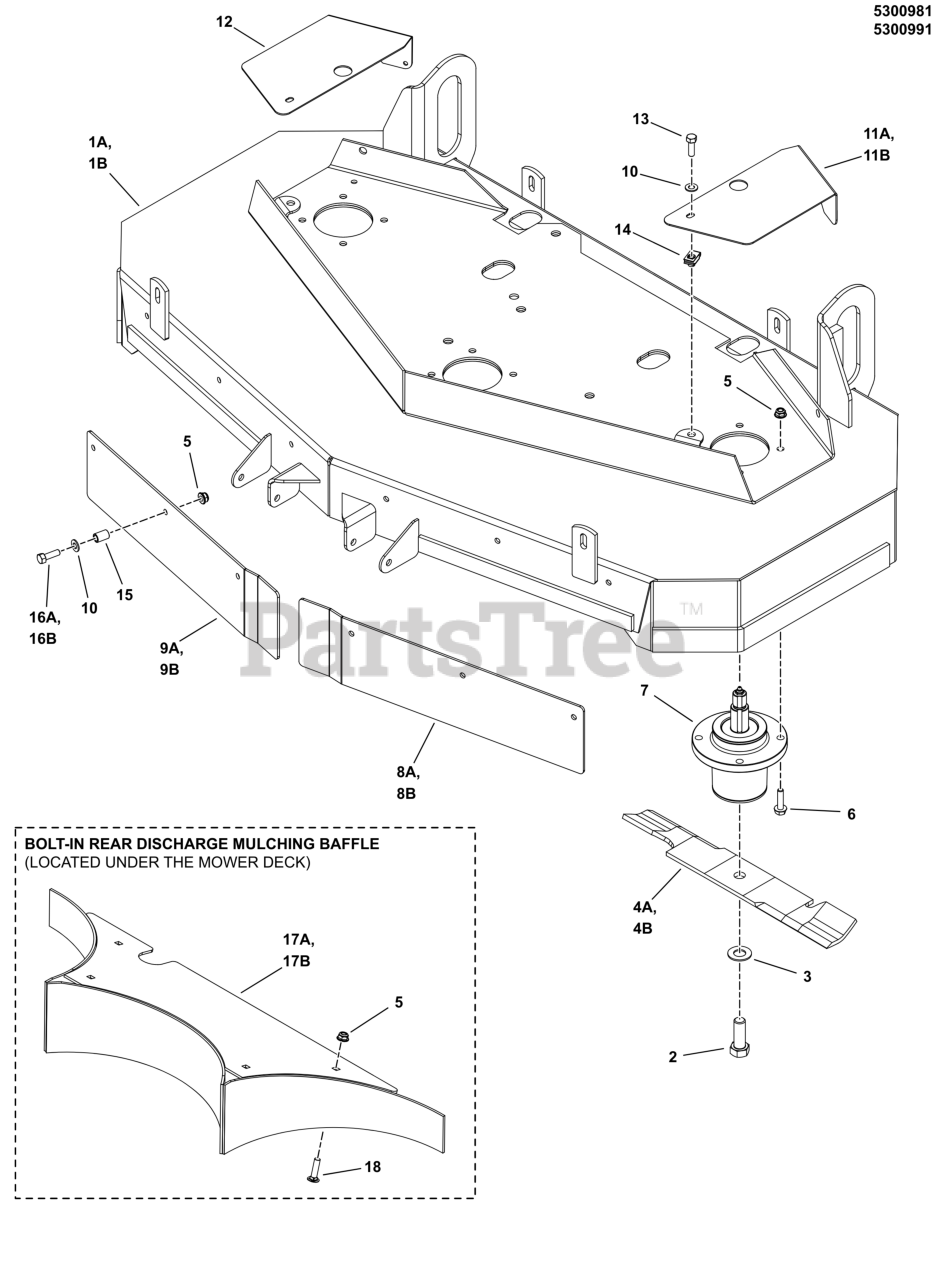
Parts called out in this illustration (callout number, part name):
1A	DECK SHELL W/DECALS
1B	DECK SHELL W/DECALS
2	BOLT, 5/8-11 X 1-3/4 GD8
3	WASHER, 5/8 GRADE 8, YZ
4A	BLADE SET, 48 DECK (SET OF 3 BLADES)
4B	BLADE, 18 (3) SET
5	NUT, 5/16-18 HEX NYLOCK FLANGE
6	BOLT, 5/16-18 X 1 1/4 FLANGE
7	ASSM, SPINDLE, LOW PROFILE
8A	BAFFLE, FRONT DISCHARGE, LH
8B	BAFFLE, FRONT DISCHARGE, LH
9A	BAFFLE, FRONT DISCHARGE, RH
9B	BAFFLE, FRONT DISCHARGE, RH
10	WASHER, 5/16" SAE
11A	GUARD, DECK, LH
11B	GUARD, DECK, LH
12	GUARD, DECK, RH
13	BOLT, 5/16-18 X 1 GD5 YZ
14	BODY CLIP, 5/16-18-7GA MATERIAL
15	SPACER, .33 X .50 X .75
16A	BOLT, 5/16-18 X 1-1/2 GD5 YZ
16B	BOLT, 5/16-18 X 3/4 GD5
17A	WELD, REAR BAFFLE
17B	WELD, REAR BAFFLE
18	BOLT, 5/16-18 X 1-1/4, CARRIAGE YZ
